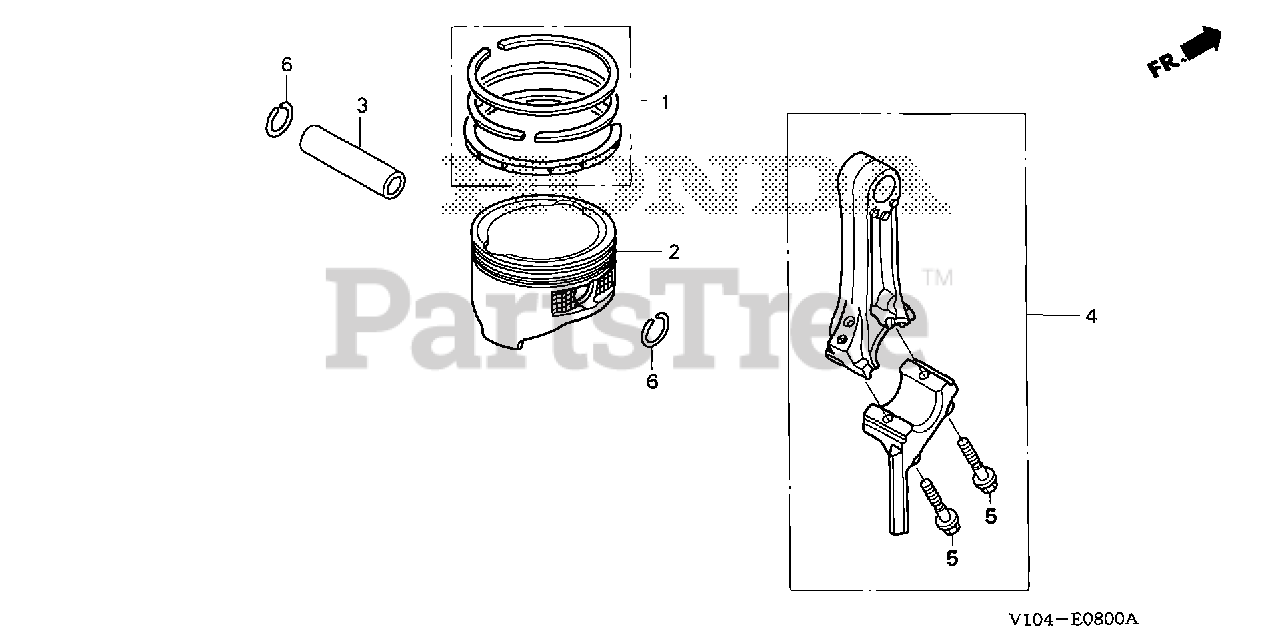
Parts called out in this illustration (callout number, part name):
1	RING SET, PISTON (RIKEN)
1	RING SET, PISTON (TEIKOKU)
1	RING SET, PISTON (STD) (TEIKOKU)
2	PISTON
3	PIN, PISTON
4	ROD ASSY., CONNECTING
5	BOLT, CONNECTING ROD
6	CLIP, PISTON PIN (13MM)
